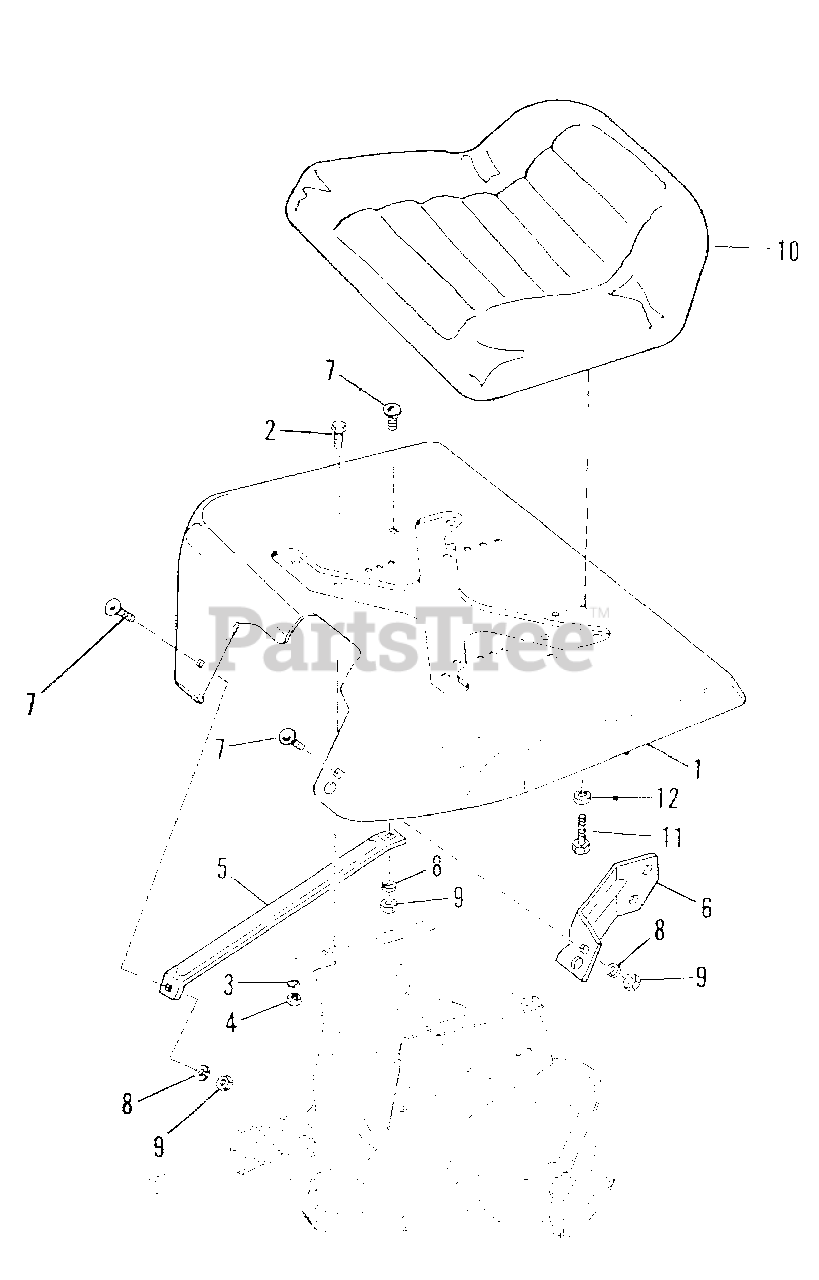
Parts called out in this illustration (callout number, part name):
1	SUPPORT, Seat
2	CAPSCREW, Hex, 5/16"-18 X 1-1/4" Large
3	LOCKWASHER, 5/16"
4	NUT, Full, Hex, 5/16-18
5	BRACE, Seat Support
7	BOLT, Carriage, 5/16-18 X 1/2" Large
8	LOCKWASHER, 5/16"
9	NUT, Full Hex, 5/16-18"
10	SEAT ASSEMBLY
11	CAPSCREW, Hex, 5/16"-18 x 3/4" Large
12	LOCKWASHER, 5/16"
